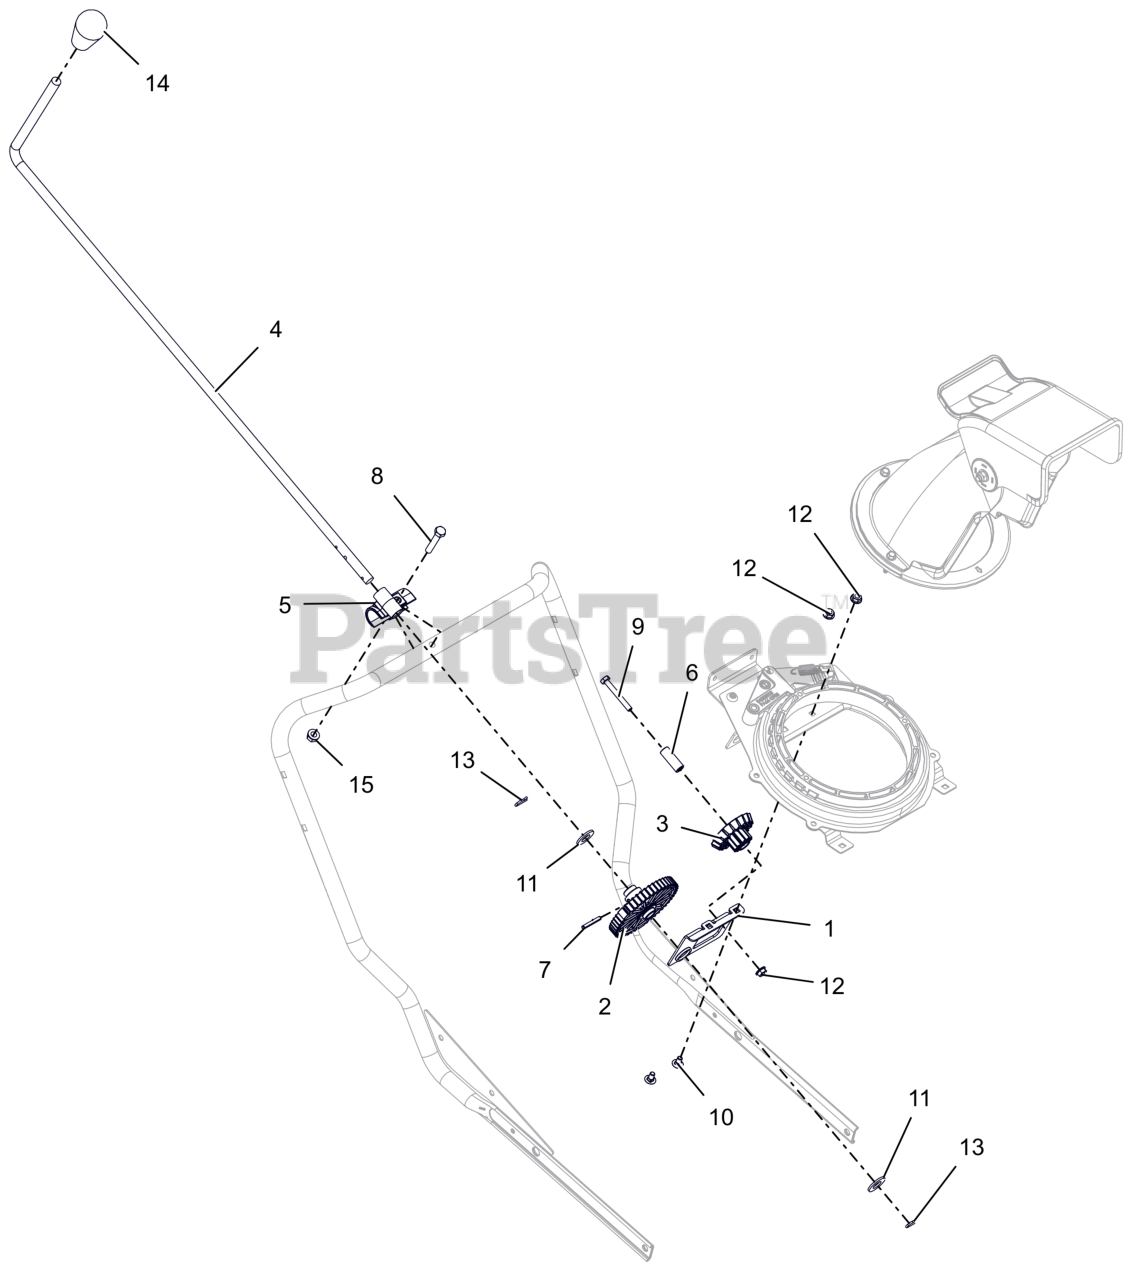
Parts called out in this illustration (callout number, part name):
1	BRKT, CHUTE ROTATION - FRONT
2	GEAR, ROTATION - REMOTE SPUR
3	GEAR, ROTATION - REMOTE COMBO
4	ROD, ROTATION - CHUTE
5	ROD, ROTATION - HOLDER
6	BSHG,SLV - .265 X .505 X 1.341
7	PIN-ROLL .188X1.25
8	BLT, HEX .31-18X1.75 G5 ZCC
9	BLT, HEX .25-20X2.00 G5 ZCC
10	BLT, RHSN .25-20X.500 G5 ZCC
11	WSHR,FLT .531X1.062X.095 ZCC
12	NUT-LK-TOP-FLG .250-20 GF ZCC
13	CLIP, SPRING
14	KNOB,SOFT-TEARDROP,PUSH-ON BLK
15	NUT-LK-TOP-FLG .312-18 GF ZCC
